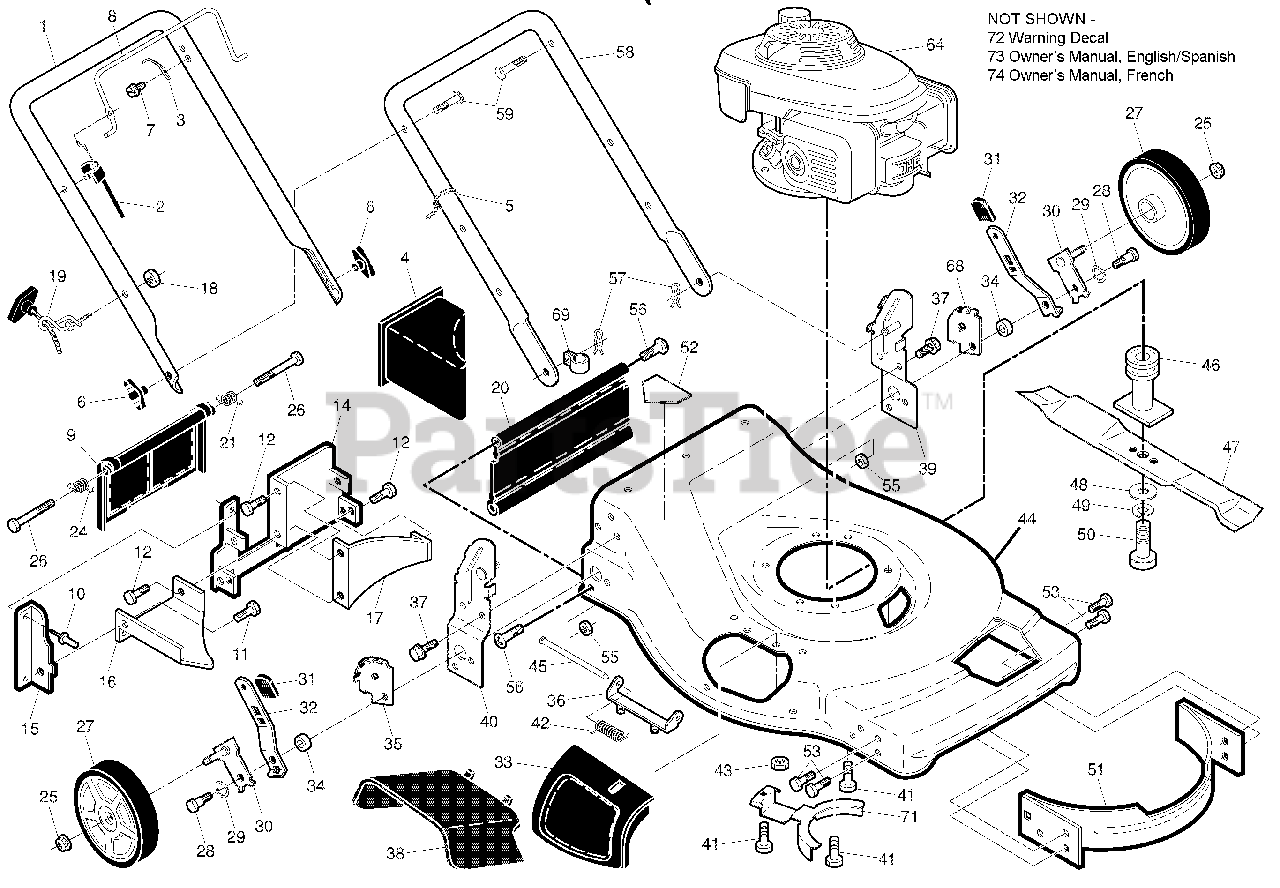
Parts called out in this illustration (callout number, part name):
1	Upper Handle
2	Engine Zone Control Cable
3	Bracket, Upstop
4	MULCH PLUG
5	Wire Tie
6	Handle Knob
7	Hex Washer Head Screw
8	CONTROL BAR
9	Rear Door Assembly
10	Pop Rivet
11	Screw, Self-Tapping
12	SCREW, SEMS, HEX HEAD 1/4-20 X
14	Back Plate
15	Side Baffle
16	Discharge Baffle
17	Rear Baffle
18	Nut, Hex
19	Rope Guide
20	REAR SKIRT
21	Spring, Rear Door, LH
24	Spring, Rear Door, RH
25	Nut, Hex
26	Bolt, Rear Door
27	REAR WHEEL
28	Bolt, Shoulder 3/8-16 x 1
29	Washer, Curved, Cylindrical
30	AXLE ARM ASSEMBLY
31	Selector Knob
32	Selector Spring, Front
33	Mulcher Door
35	WHEEL ADJUSTING BRKT LH
36	Hinge Bracket Assembly
37	Screw, Sems, Thread Cutting 5/
38	Discharge Def ector
39	HANDLE BRACKET ASSEMBLY RH
40	HANDLE BRACKET ASSEMBLY LH
41	Screw, Hex Head, Threaded, Rol
42	Spring, Torsion
43	Locknut, Hex 1/4-20
44	Kit, Housing
45	Rod, Hinge
46	PULLEY, BLADE ADAPTER
48	Hardened Washer
49	Helical Lockwasher
50	Screw, Hex Head, Grade 8 3/8-2
51	Kit, Front Baffle
52	Danger Decal
53	SCREW.HEX.WASHEAD.1/4-20 X 3/8
55	NUT.CENTERLOCK.3/8-16 UNC.
56	Hinge Screw
57	Hairpin Cotter
58	Lower Handle
59	Handle Bolt
64	Engine, Honda, Model Number GCV160-LAS3A (For engine service and replacement parts,
68	WHEEL ADJUSTING BRKT RH
69	Clip, Cable
71	BELT KEEPER
